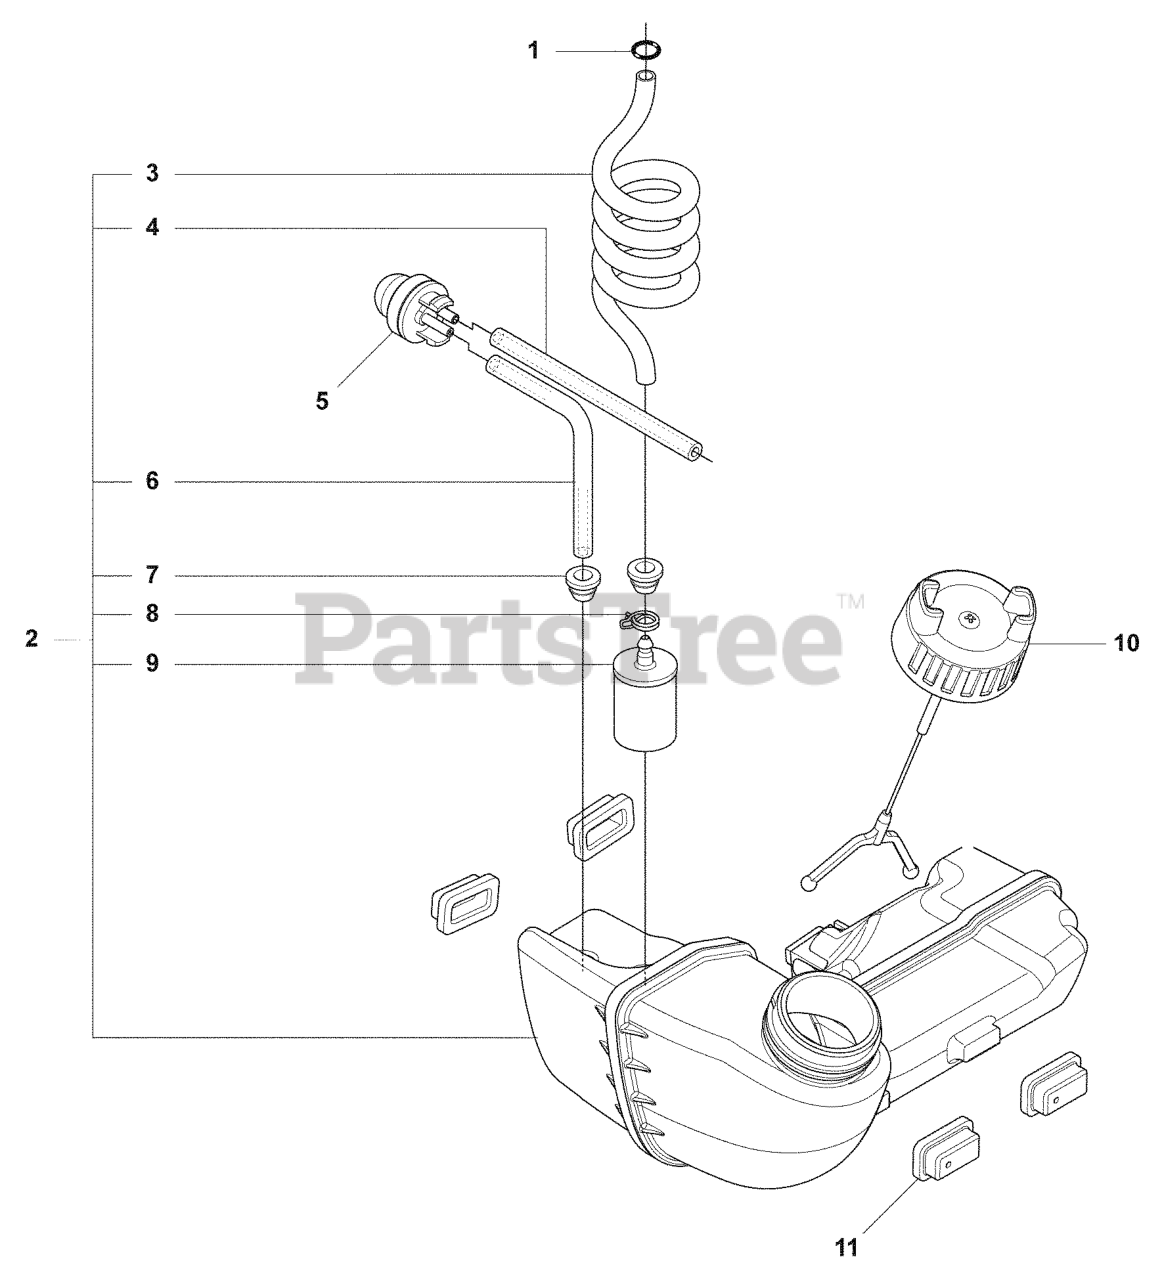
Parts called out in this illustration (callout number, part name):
2	FUEL TANK ASSY
3	FUEL HOSE
4	HOSE.FUEL L=102
5	AIR PURGE BUBBLE
6	HOSE.FUEL L=102
7	FUEL TANK BUSHING
8	HOSE CLAMP
9	RP FUEL FILTER
10	%FUEL CAP
